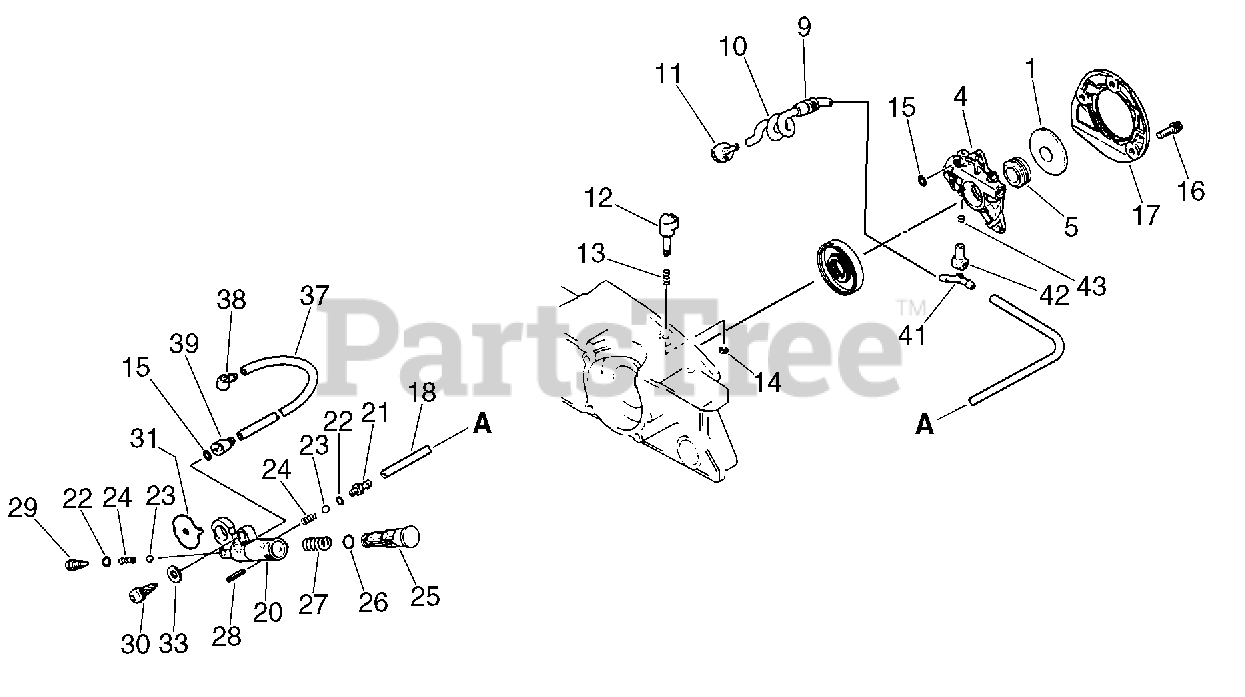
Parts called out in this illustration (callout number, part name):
1	WASHER - 12
4	AUTO-OILER ASSY
5	WORM (P)
10	PIPE - OIL
11	FILTER, OIL
12	DIAL, AUTO-OILER
14	RING, RETAINING - 3
15	O-RING - 3
16	SCREW - 4X12
17	COVER, OIL PUMP
18	PIPE - 3X6X200 -- BLACK
18	OIL PUMP ASSY
20	BODY, OIL PUMP
23	VALVE, BALL
24	SPRING, VALVE
25	PISTON, MANUAL
26	O-RING - 7
28	PIN - SPRING -- 2X16
29	ADAPTER, OIL PUMP
30	SCREW - 5X20
31	BARCKET, OIL PUMP
33	WASHER - 5
37	PIPE, OIL - 3X6X125
38	CONNECTOR, PIPE
39	CONNECTOR, PIPE
41	CONNECTOR, PIPE
42	PIPE - 3X6X20 -- BLACK
43	CLIP - 6.5
